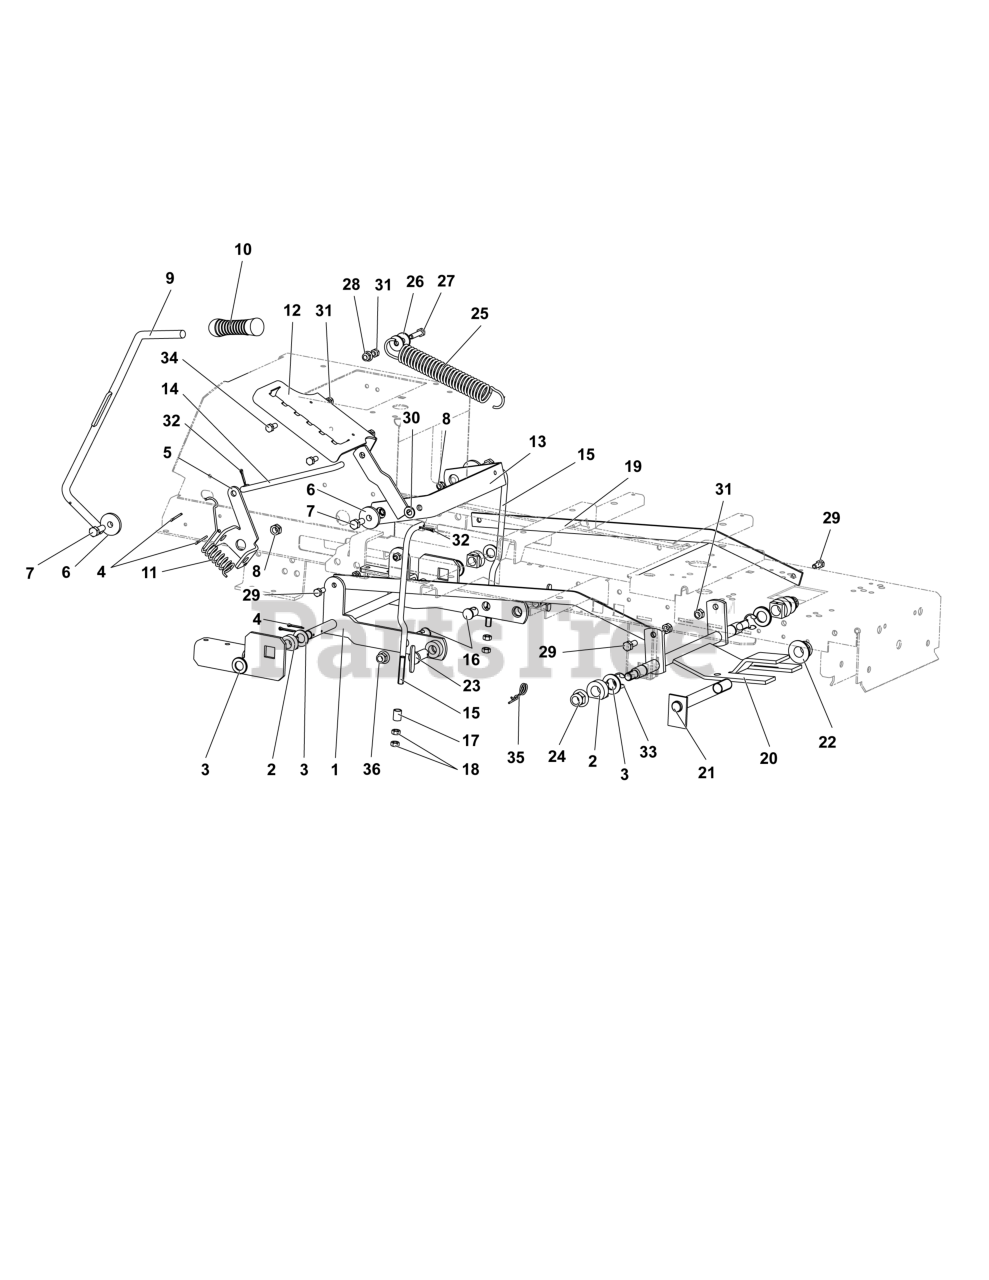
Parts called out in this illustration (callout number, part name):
1	BRACKET, Lifting
10	GRIP, Handle
12	BRACKET, Lifting
14	BAR, Lifting
15	BAR, Lifting
20	BRACKET, Lifting
